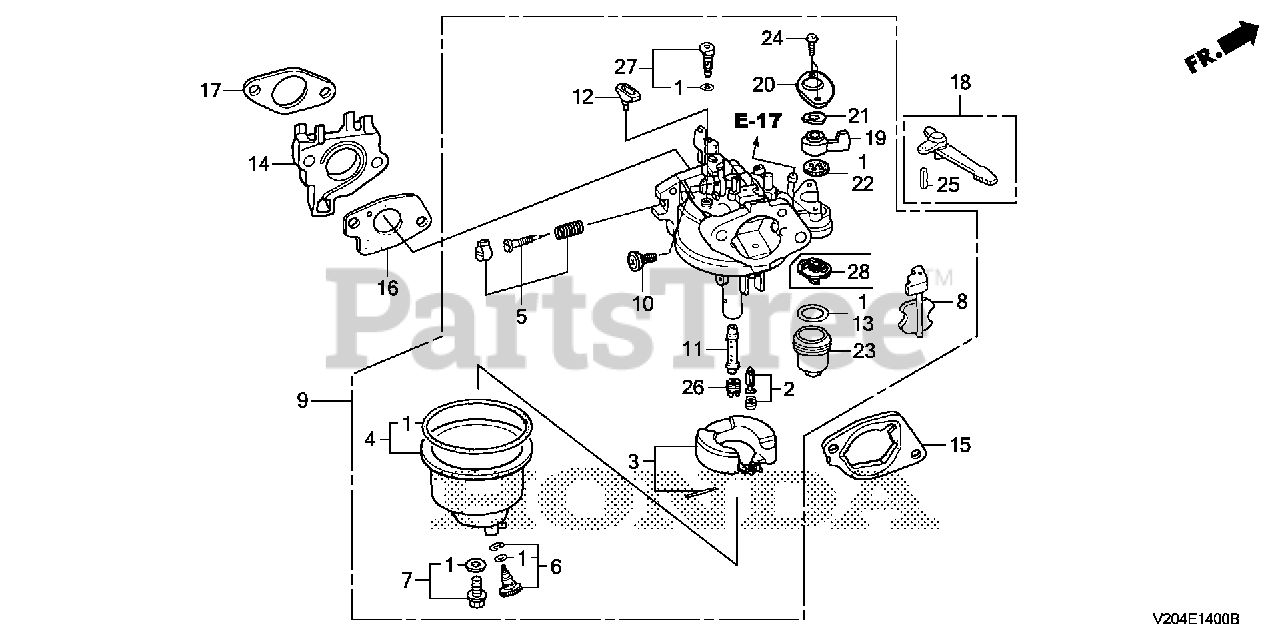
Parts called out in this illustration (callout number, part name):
1	GASKET SET (CARBURETOR NO.)
2	VALVE SET, FLOAT
3	FLOAT SET
4	CHAMBER SET, FLOAT (CARBURETOR NO.)
5	SCREW SET
6	SCREW SET, DRAIN (CARBURETOR NO.)
7	SCREW SET
8	CHOKE SET
9	CARBURETOR ASSY. (BE70J A)
10	SCREW, THROTTLE STOP
11	NOZZLE, MAIN (CARBURETOR NO.)
12	COLLAR, SET
13	GASKET, FUEL STRAINER CUP
14	INSULATOR, CARBURETOR
15	SPACER, CARBURETOR
16	GASKET, CARBURETOR
17	GASKET, INSULATOR
18	LEVER, CHOKE (STD)
19	LEVER, VALVE
20	PLATE, LEVER SETTING (CARBURETOR NO.)
21	SPRING, PETCOCK LEVER (CARBURETOR NO.)
22	GASKET, VALVE
23	CUP, FUEL STRAINER
24	SCREW, PAN (3X6)
25	PIN, SPRING (2X12)
26	JET, MAIN (#88) Use up to Engine SN BE81B B.
26	JET, MAIN (#90) Use from Engine SN BE81B C.
26	JET, MAIN (#92)
27	JET SET, PILOT (#40) (ADVENTURE GREEN) (CARBURETOR NO.)
